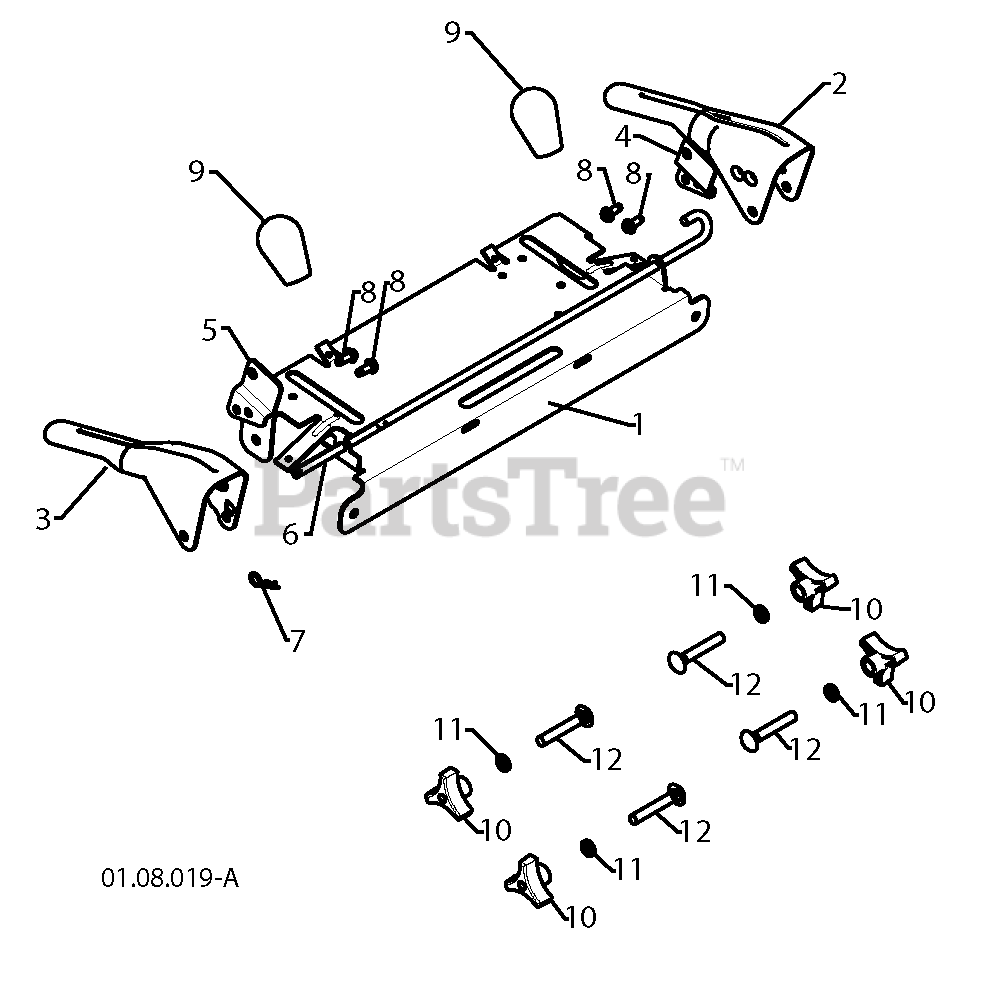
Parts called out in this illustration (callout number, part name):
1	PANEL.CONTROL.SNOW.BL
2	LEVER.CONTROL.LH.BLACK
3	LEVER.CONTROL.RH.GREY
4	BRACKET.ROD.TRACT.LH.ZINC
5	BRACKET.ROD.IMP.RH.ZINC
6	BAIL.CONTROL.INTERLOCK
7	SPRING RETAINER
8	SCREW 14-20 X 5/8
9	KNOB.OVERMOLD.DS.HUSQVARNA/BLK
10	KNOB.HANDLE.3/8.TRI-POINT.BLAC
11	WASHER
12	BOLT 3/8-16 X 2-1/4
